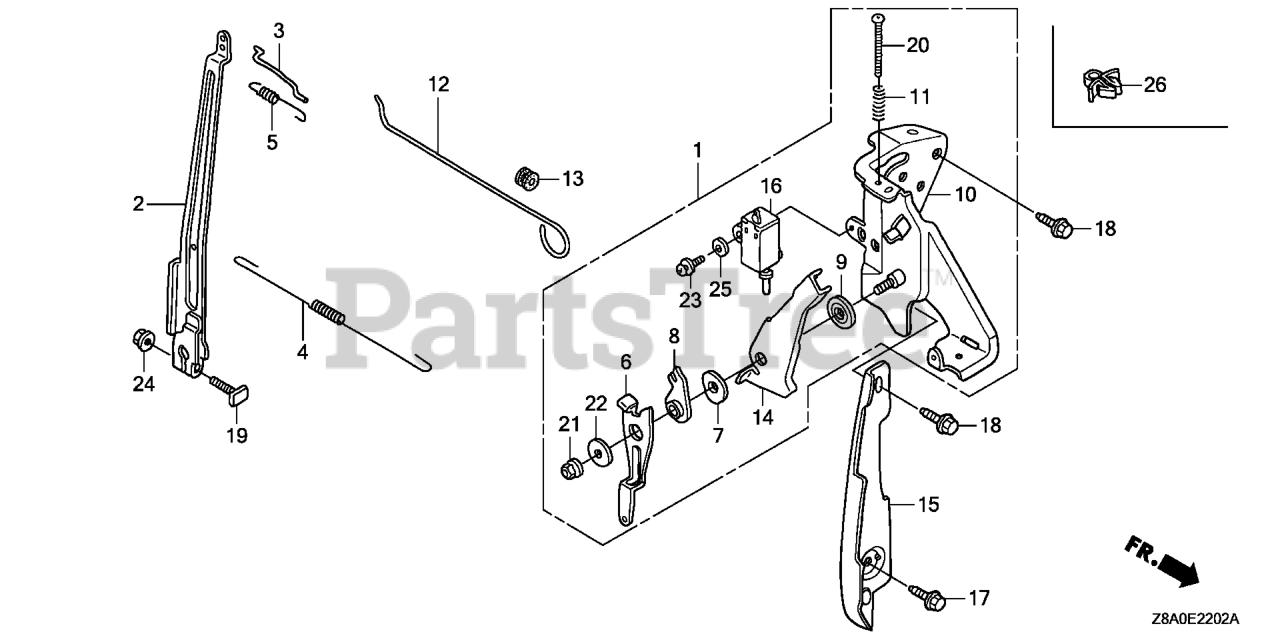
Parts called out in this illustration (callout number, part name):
1	CONTROL ASSY.
2	ARM, GOVERNOR
3	ROD, GOVERNOR
4	SPRING, GOVERNOR
5	SPRING, THROTTLE RETURN
6	LEVER, CONTROL
7	SPRING, LEVER
8	WASHER, CONTROL LEVER
9	SPACER, CONTROL LEVER
10	BASE, CONTROL
11	SPRING, CONTROL ADJUSTING Use from Engine SN 2327377.
12	ROD, CHOKE CONTROL
13	GROMMET, CHOKE ROD
14	LEVER, STOP
15	PLATE, SIDE
16	SWITCH ASSY., ENGINE STOP (N.O)
17	BOLT, FLANGE (6X12) (CT200)
18	BOLT, FLANGE (6X14)
19	BOLT, GOVERNOR ARM
20	SCREW, ADJUST
21	NUT, SELF-LOCK (6MM)
22	WASHER, WHEEL (6MM)
23	SCREW-WASHER (4X12)
24	NUT, FLANGE (6MM)
25	WASHER, PLAIN (4MM)
26	CLIP, CABLE (A)
